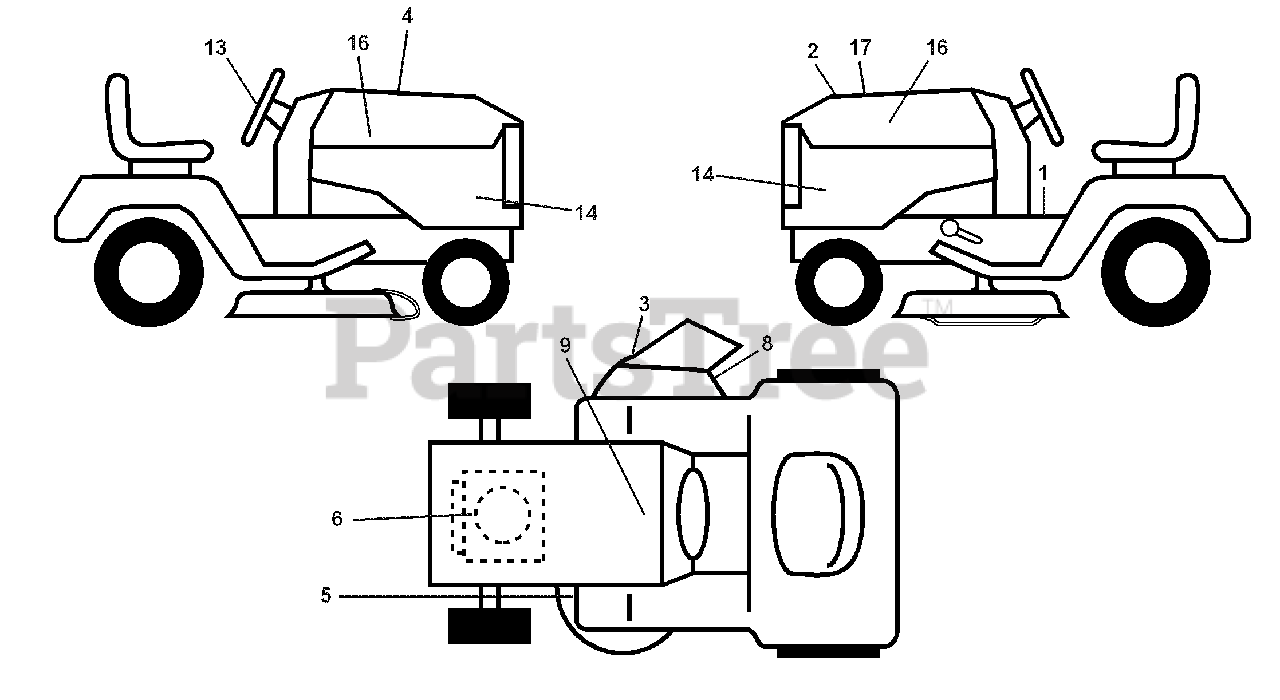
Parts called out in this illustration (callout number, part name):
1	Decal, Operator's
2	Decal, Hood Insert
3	Decal, Warning
4	Decal, Hood Cust Resp
5	Decal, Caution
6	Decal, Eng. HP
8	Decal, Mower Sch.
9	Decal, Battery Dnge/Poi
13	Decal, Steering Whl
14	Decal, Panel Side
16	Decal, Hood Logo
17	Decal, Replacement
